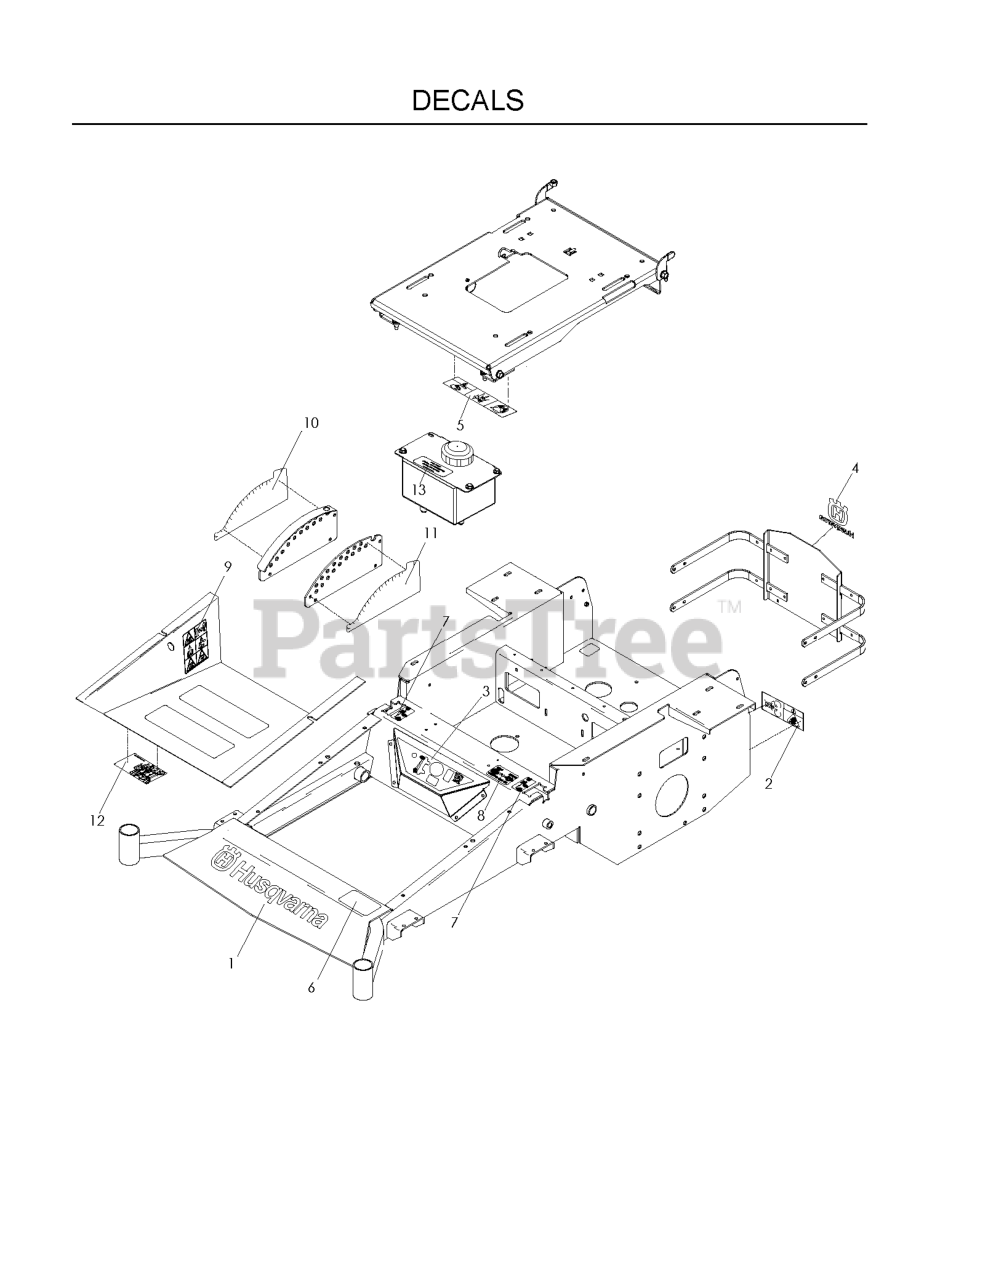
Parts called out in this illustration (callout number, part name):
1	DECAL, HUSQ 15" BLUE
2	DECAL, BELT DRIVE
3	DECAL, CONSOLE
4	DECAL, CROWN H 5-1/4 SILVER
5	EURO DECAL-BATTERY WARNIN6
6	DECAL, LZ25
7	DECAL, MOTION CONTROL
8	DECAL, F.S.T.
9	DECAL, WARNING
10	DECAL, HEIGHT, LZEBZE
11	DECAL, HEIGHT, LZEBZE
12	DECAL, SERVICE
13	DECAL, OIL TANK
